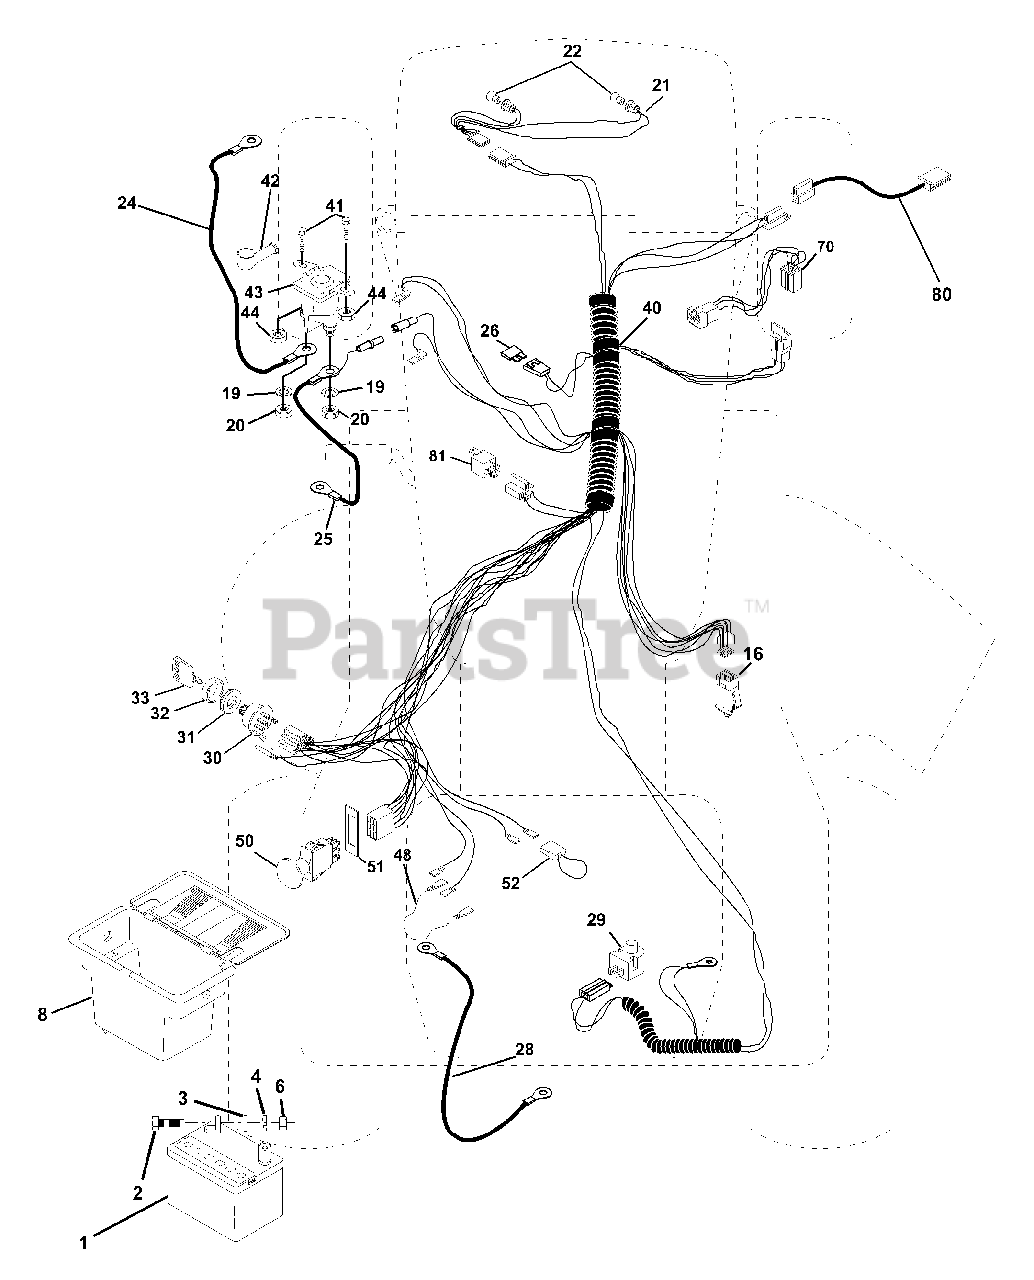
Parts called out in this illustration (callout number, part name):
1	Battery 12 Volt 25 AMP
2	Bolt Hex Hd 1/4-20unc X 3/4
3	Washer 9/32 X 5/8 X 16 Ga.
4	Washer Lock Hvy Helical 1/4
6	Nut Fin Hex 1/4-20 Unc
8	Case Battery Mech Hinge
16	Switch Interlock Push-In
19	Washer Lock 1/4
20	Nut Jam Hex 1/4-20 Unc
21	Harness Asm Light W/4152j
22	Bulb Light #1156
24	Cable Battery 6 Ga 11" red
25	Cable Battery 6 Ga 44" red w/16 wire
26	Fuse 30 AMP Auto Green
28	Cable Ground 6 Ga 12" black
29	Switch Plunger Normal OP Olive
30	Switch Ign 4 pos w/lights
31	Nut Ignition
32	Cover Sw Ignition
33	Key Ign Modelled Generic
40	Harness Ign.
41	Bolt Blk Fin Hex 1/4 - 20 x 1/2
42	Cover Terminal Red
43	Solenoid
44	Nut Keps Hex 1/4-20 Unc
48	Adapter Ammeter Rectangular
50	Switch PTO 3PDT Black Delta 96
51	Ring Retainer PTO
52	Protection Wire Loop
70	Harness, Eng. kohl Cmd-L Dual
80	Harness Clutch EVX
88	Harness Eng Koh Cv15 Stator
